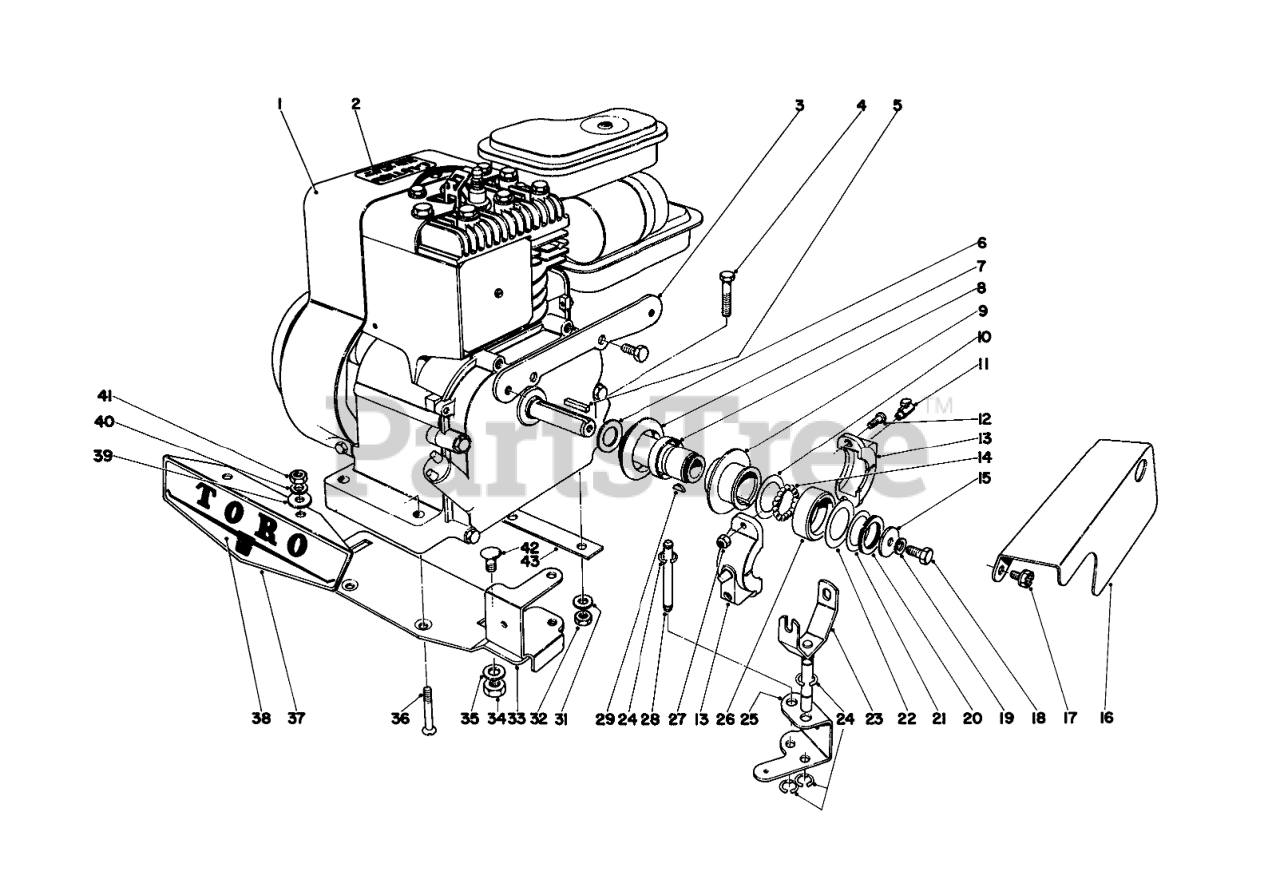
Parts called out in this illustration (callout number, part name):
1	Engine
2	Decal
3	Bracket
4	Screw
5	KEY-SQUARE
6	Washer
7	CLUTCH BODY ASM
8	IDLER BUSHING
9	SLIDING FLANGE
10	Thrust Washer
11	OIL CUP (OBS)
12	SCREW
13	Slip Ring
14	BALL-STEEL
15	Washer
16	Belt Guard
17	Screw
18	SCREW-HH
19	WASHER-LOCK
20	Snap Ring
21	WASHER
22	WASHER
23	SHIFT FORK ASM R
24	RING-RETAINING, EXT
25	SHIFT FORK BRACKET
26	Shift Collar
27	NUT-LOCK
28	Pivot Shaft
29	KEY-WOODRUFF
31	WASHER-PLAIN
32	NUT-LOCK NI
33	Clutch Mounting Plate
34	Nut
35	WASHER-PLAIN
36	Screw
37	Name Plate
38	Decal
39	WASHER-FLAT
40	WASHER-LOCK
41	NUT-HEX
42	BOLT-CARR
